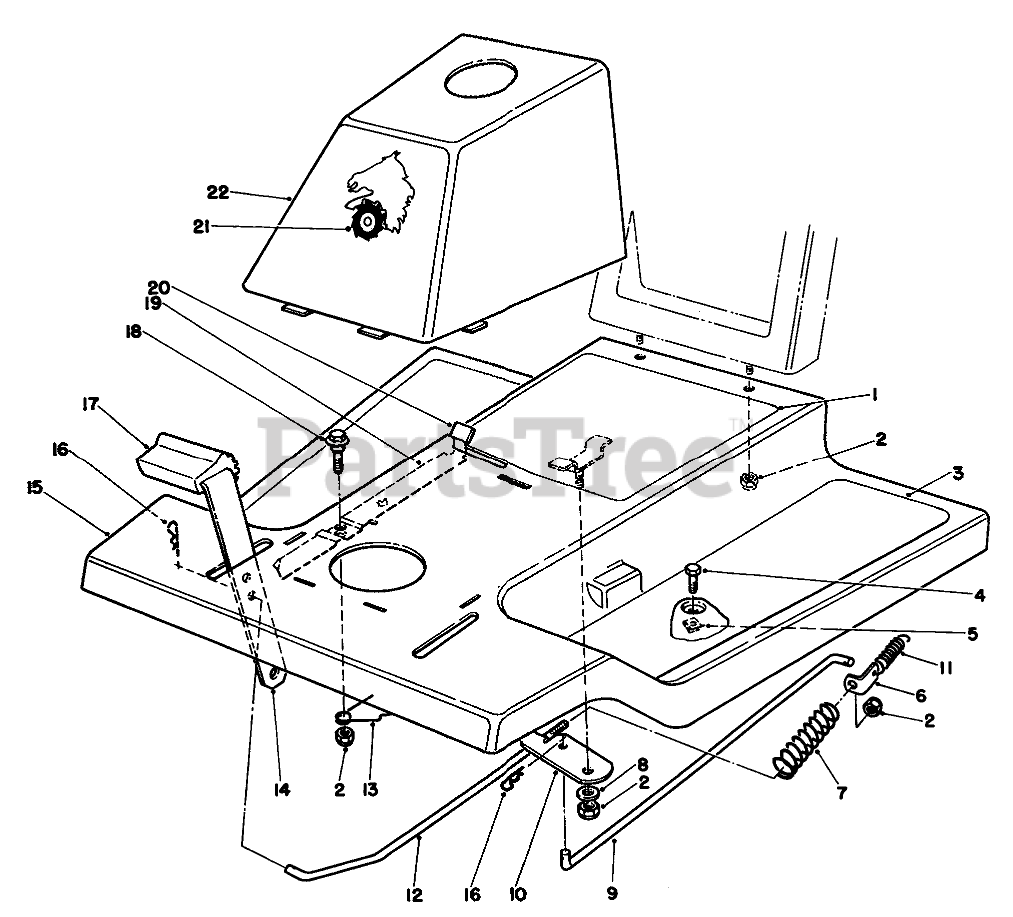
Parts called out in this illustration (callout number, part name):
1	DECAL - INSTRUCTION
2	NUT-LOCK, NI
3	TREAD-FOOT
4	SCREW-HH
5	NUT-TINNERMAN
6	BRACKET-BRAKE RETURN
7	SPRING-TRACTION BRAKE
8	WASHER-PIVOT
9	ROD-TRANS BRAKE
10	Lever-Brake, Bellcrank
11	SPRING-IDLER
12	ROD-FRONT BRAKE
13	SPRING-PARKING BRAKE
14	Pedal-Brake & Clutch
15	Body W.A.-Front
16	PIN-COTTER
17	PAD-PEDAL
18	SCREW-SHOULDER
19	Parking Brake
20	TIP-PARKING BRAKE
21	DECAL - HORSEHEAD
22	Tower (Incl. Ref. #21)
